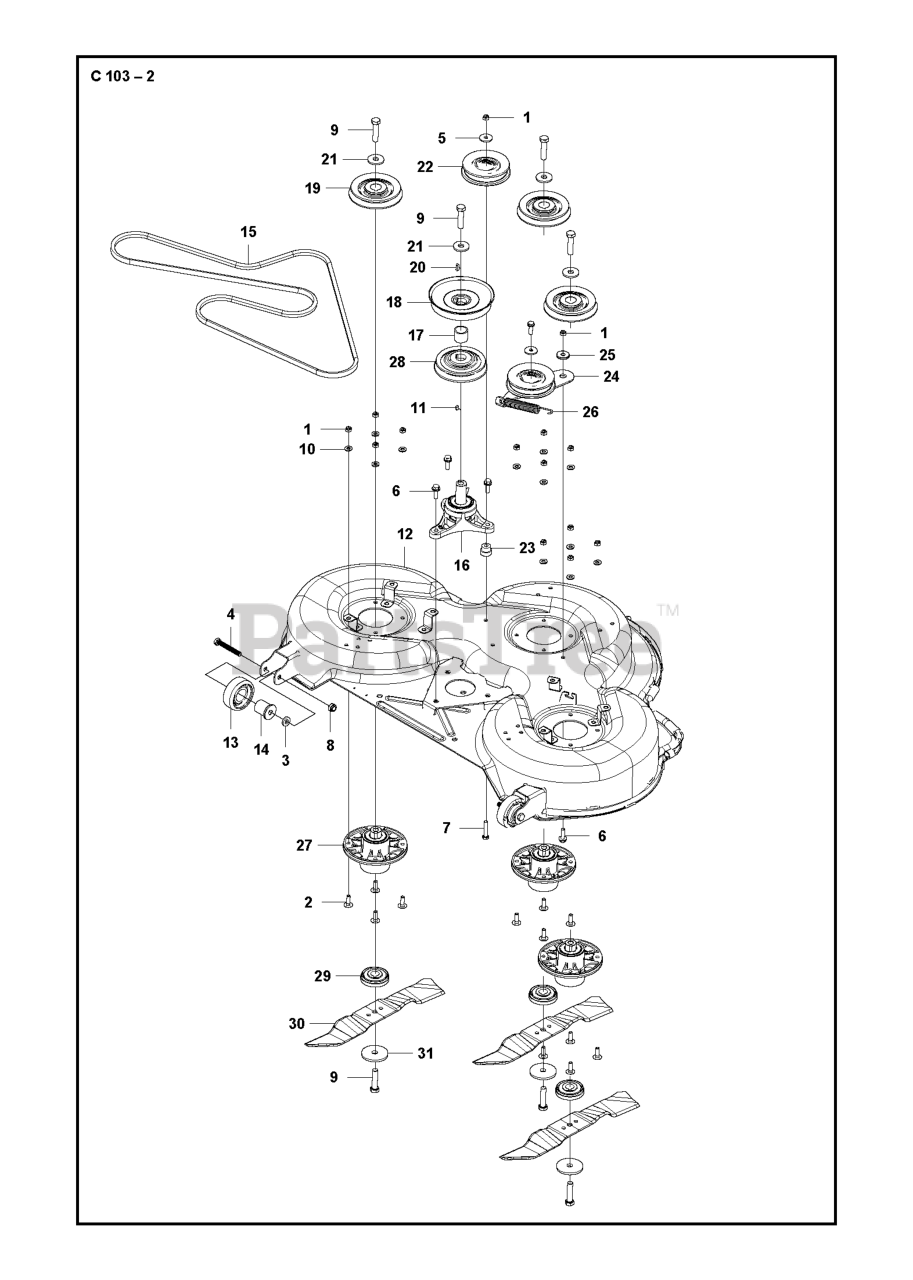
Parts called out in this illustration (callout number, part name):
1	LOCKNUT M8
6	BOLT
10	WASHER BRB 8.4X17
25	WASHER PLASTIC ASSY
